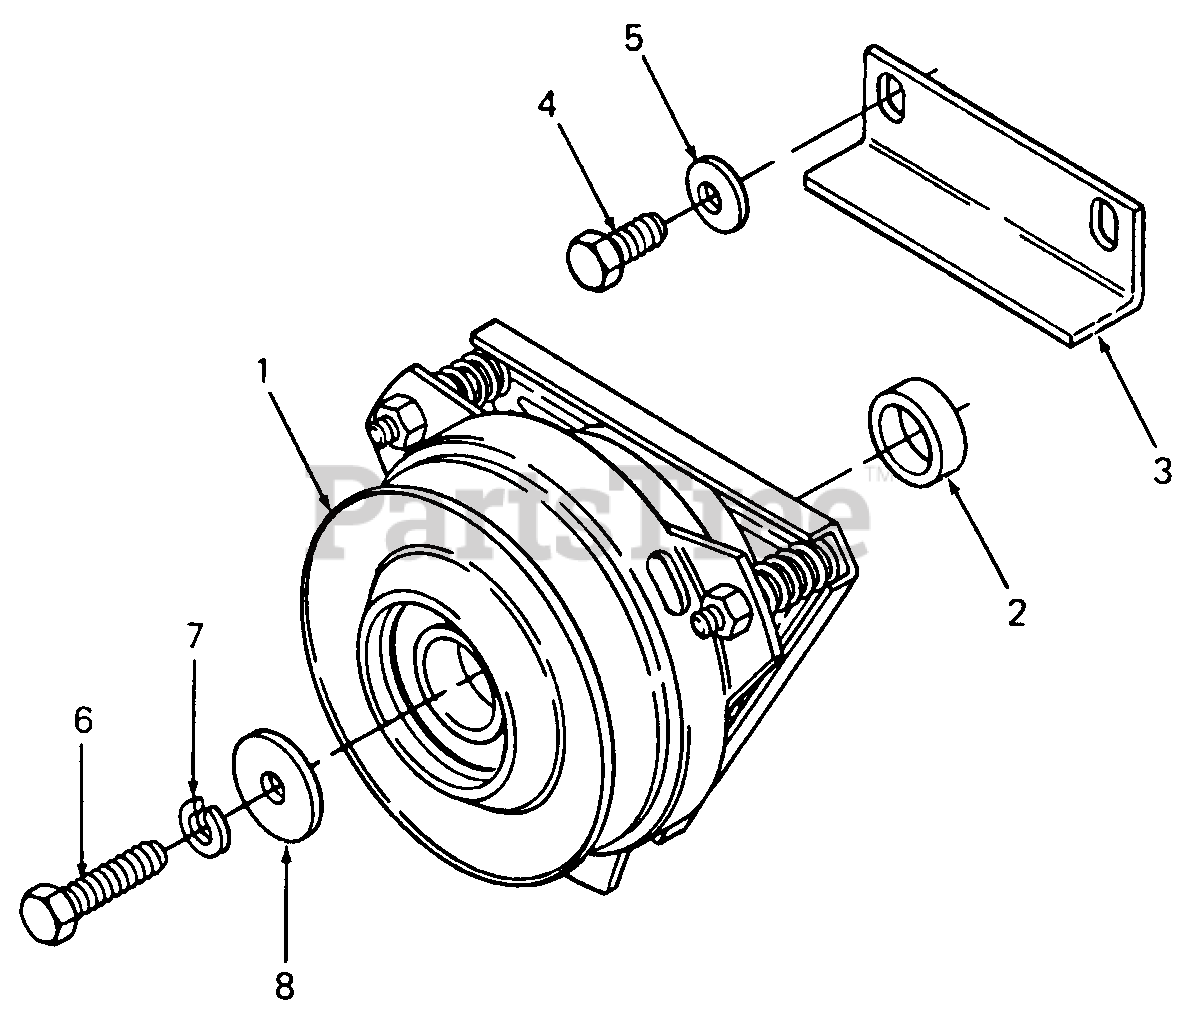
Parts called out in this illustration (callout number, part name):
1	Clutch, PTO
2	Spacer, 1.0 X 1.37 X .47 Lg
3	Bracket, Torque
4	Screw, Hex Cap, 7/16-14 X .75 Lg GR5
5	Washer, Bell, .45 X 1.0 X .062 Thk
6	Screw, Hex Cap, 7/16-20 X 1.5 Lg GR5
7	Washer, Lock, 7/16
8	Washer, Flat, .47 X 1.5 X .225 Thk
